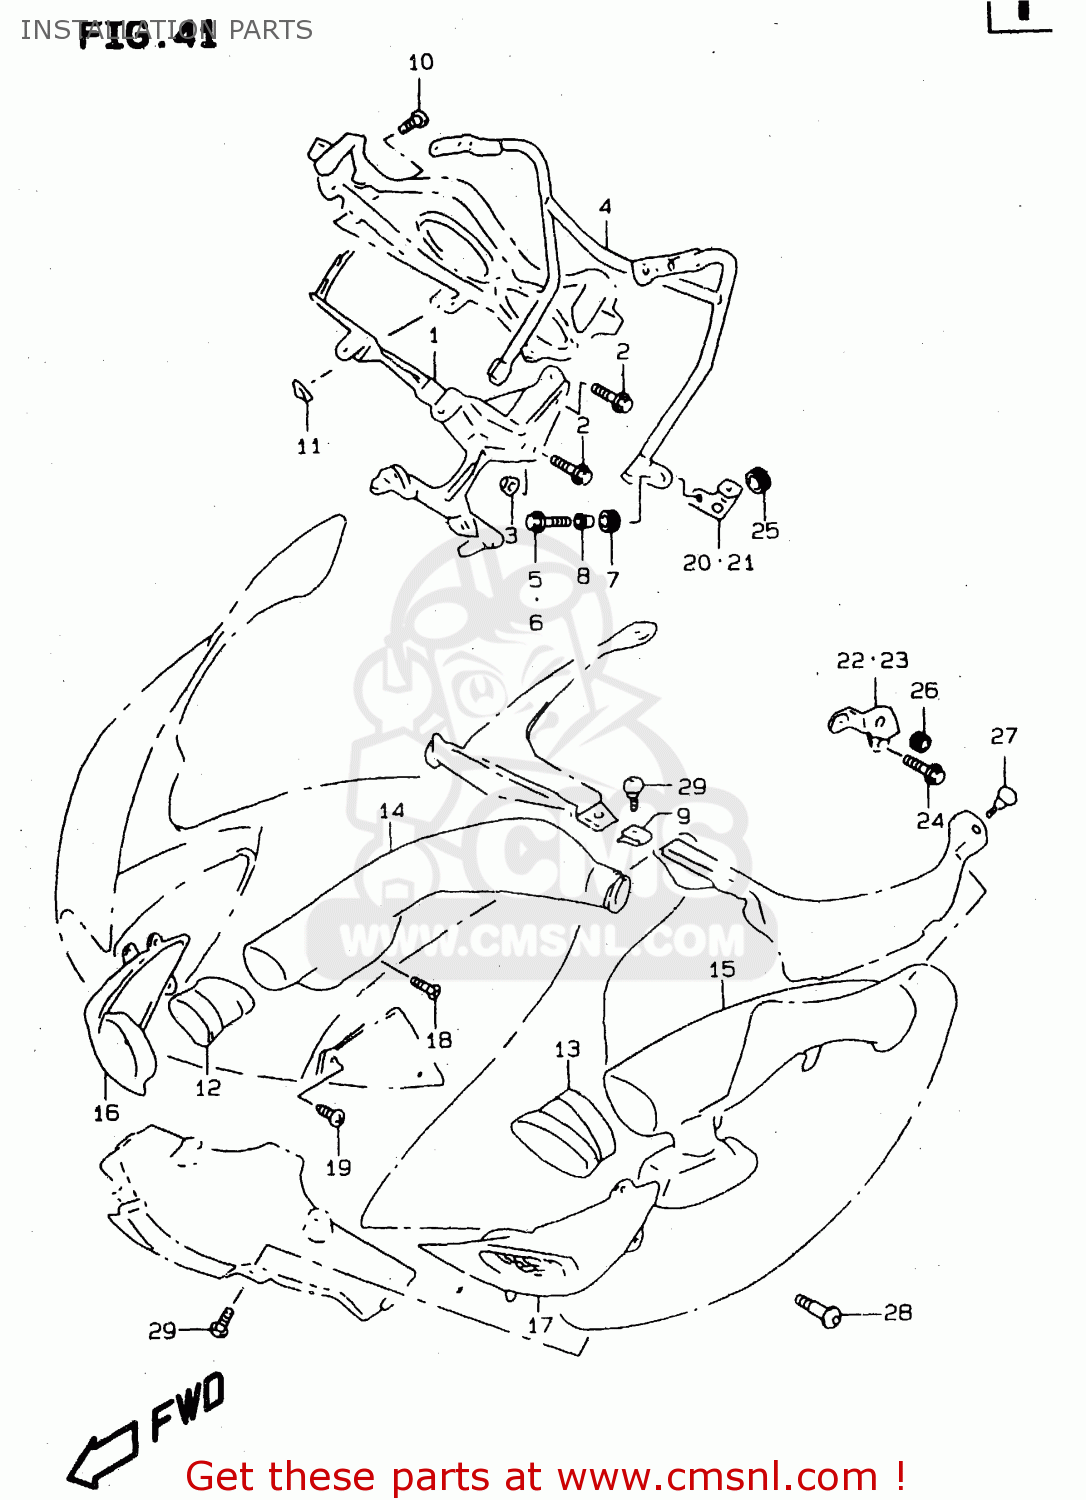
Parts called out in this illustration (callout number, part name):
1	BRACE,COWLING
2	BOLT
3	NUT
4	BRACE COMP,REAR VIEW MIRROR
5	BOLT 6X20
6	BOLT(6X30)
7	CUSHION
8	WASHER,MIRROR BRACE,IN
9	NUT,HEADLAMP HOUSING,UPPER
10	SCREW
11	NUT
12	JOINT,AIR INTAKE,R
13	JOINT,AIR INTAKE,L
14	PIPE,AIR INTAKE,R
15	PIPE,AIR INTAKE,L
16	COVER,INTAKE,R
17	COVER,INTAKE,L
18	SCREW
19	SCREW
20	BRACKET,SIDE COWLING UP,R
21	BRACKET,SIDE COWLING UP,L
22	BRACKET,SIDE COWLING RR,R
23	BRACKET,SIDE COWLING RR,L
24	BOLT
25	CUSHION
26	CUSHION
27	SCREW(5X16)
28	SCREW(6X20)
29	SCREW(5X16)
